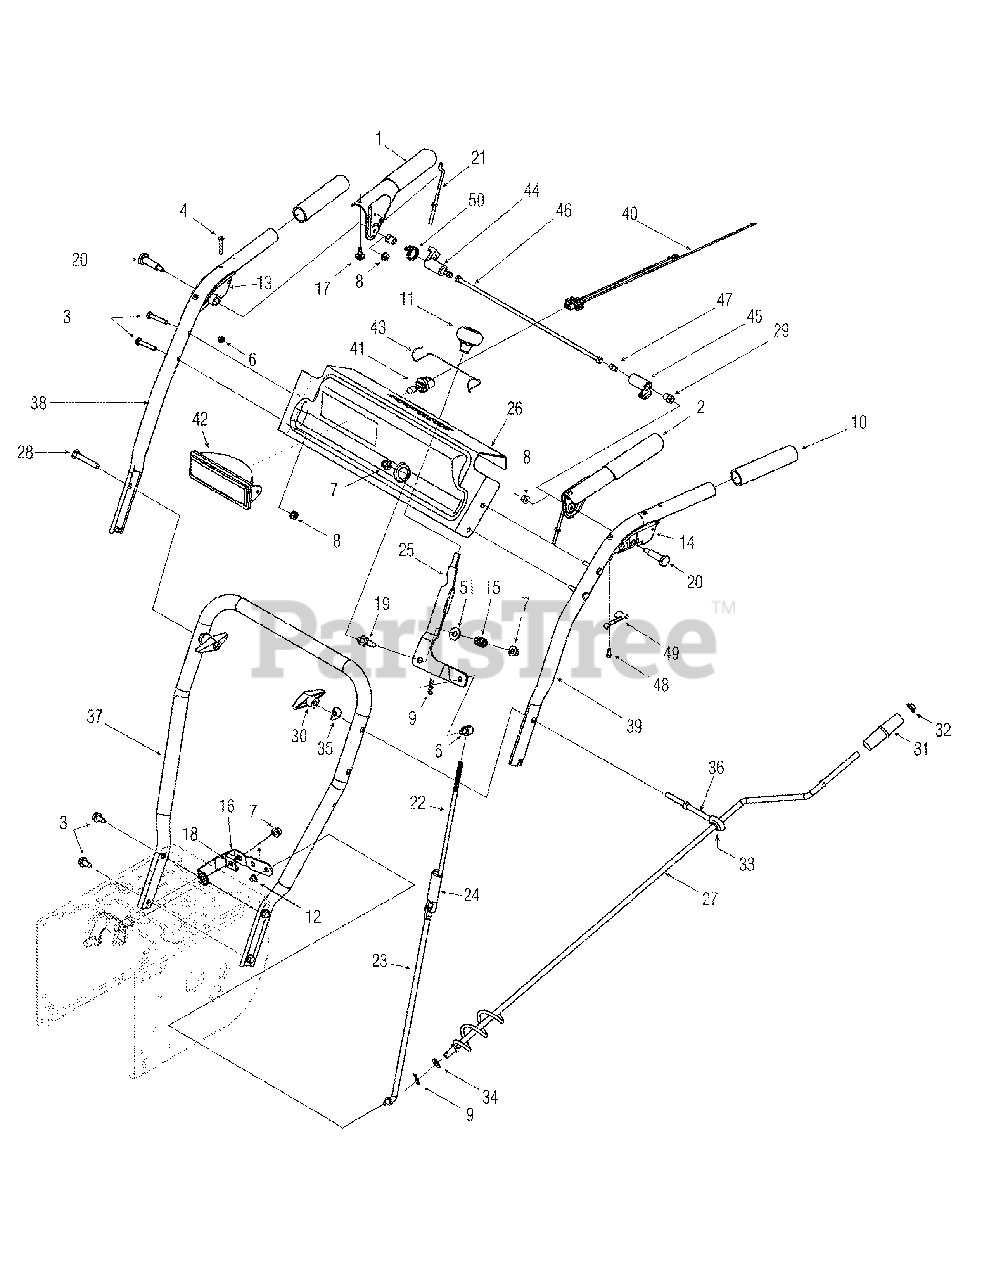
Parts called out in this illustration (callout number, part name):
1	Handle Ass'y, Engagement RH Black
2	Handle Ass'y, Engagement, LH Black
3	Screw, Self-tapping, 5/16-12, 0.750
4	Screw, Machine, #10-24, 1.375
5	Ferrule, 5/16-18 x .312 Diameter
6	Nut, Hex Lock, #10-24, Gr2, Nylon
7	Nut, Flange Lock, 5/16-18, Grf, Nylon
8	Nut, Flange Lock, 1/4-20, Grf, Nylon
9	Pin, Cotter, .072 Diameter x 1.13
10	Grip, 1.0 ID x 5.0
11	Shift Knob, Black
12	Nut, Push, 5/16
13	Handle, Clutch Lock, RH
14	Handle, Clutch Lock, LH
15	Spring, Compression, .39x.60 x .88
16	Spring, Shift, Lever
17	Bumper, Rubber, .62 OD x .22
18	Bracket, Shift Spacer
19	Bolt, Shoulder, 5/16-18 x 0.830
20	Screw, Shoulder, .437 x 1.345, 1/4-20
21	Z Fitting, Cable
22	Shift Rod Kit
22	Shift Rod Upper
23	Rod, Shift, Lower
24	Connector Sleeve, Shift Rod
24	Connector Sleeve
25	Lever, Shift, Speed
28	Screw, Carriage, 5/16-18, 2.25, Gr5
29	Shoulder Nut, Hex, 1/4-20
30	Knob Assembly, Wing Nut, 5/16-18
31	Crank Knob, 1.0 Diameter x 3.2, Black
32	Cap, Push, 3/8 Rod
33	Grommet, .44 ID x .94 OD x .50
34	Washer, Flat, .375 x .738 x .063
35	Washer, Saddle, 320 x .93 x .060
36	Eye Bolt, Chute Crank
40	Harness, Headlight
41	Lamp, Halogen, 12V, 27W
42	Lens Assembly, Lamp
43	Retainer, Lens
44	Plate, Lock
45	Cam, Lock
46	Rod, Pivot
47	Screw, 1/4-20, .375
48	Screw, #8-18 x .50
49	Spring, Control Lever Lock
50	Spring, Torsion, .8156 x .3038
51	Washer, Flat, .385 x .870 x .092
